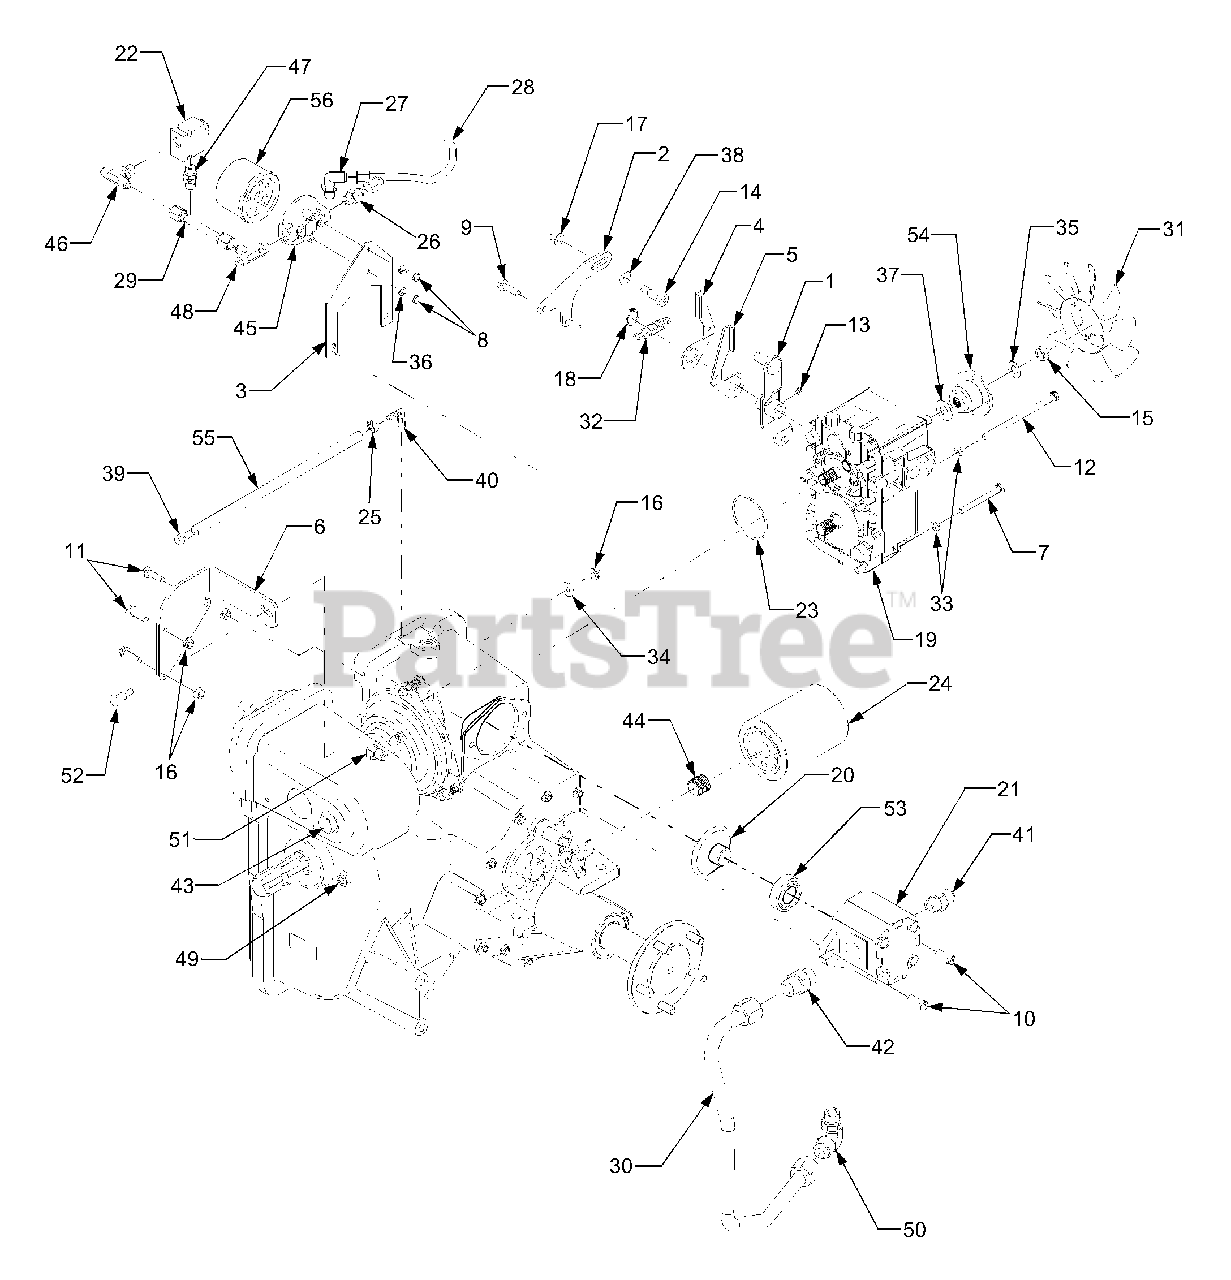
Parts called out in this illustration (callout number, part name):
1	Arm, Hydro
2	Bracket, Return
3	Bracket, Filter Mounting
4	Arm, Neutral - RH
5	Arm, Neutral - LH
6	Bracket, Clutch Torque
7	Screw, Hex Cap, 5/16-18 x 3.0 GR5
8	Screw, Hex Cap, 1/4-20 x .62 GR5
9	Screw, Hex Wash. Hd. Tapp, 5/16-18 x 1.25 GR5
10	Screw, Socket Hd. 3/8-16 x 1.0
11	Screw, Hex Flange, 5/16-18 x 1.5 GR5
12	Screw, Hex Cap Lock, 5/16-18 x 5.5 GR5
13	Screw, Set - Lock 5/16 x .5 GR5
14	Screw, Shoulder, .497 x .750: 3/8-16
15	Nut, Hex Patch Lock, 1/2-20
16	Nut, Hex Flange Lock, 5/16-18 GR5
17	Nut, Hex Flange Lock, 3/8-16
18	Ring, Retaining
19	Pump, Hydrostatic Transmission
20	Gear, Bevel, 35T
21	Pump, Auxiliary Hydraulic
22	Valve, Check
23	O-Ring, 2.425 ID x .103
24	Filter, Oil - Hydraulic System
25	Clamp, Hose
26	Fitting, Straight
27	Fitting, 90 Degree
28	Tube, Hydro Inlet
29	Tube, Filter Inlet
30	Tube, Aux. Pump Inlet
31	Fan, Transmission Cooling
32	Spring, Extension, .50 x 1.975 x.072
33	Washer, Lock, 5/16
34	Washer, Bell., .34 x .872 x .06
35	Washer, Belleville
36	Washer, Lock, 1/4
37	Washer, Flat, .56 x 1.0 x .04
38	Washer, Thrust, .375 x .812 x .06
39	Vent, 3/8 Dia
40	Fitting, Elbow
41	Fitting, Hyd. Adapter w/O-ring
42	Fitting, Hyd. Adapter w/O-ring
43	Fitting, Plug
44	Fitting, Filter Nipple
45	Adapter, Oil Filter
46	Fitting, Branch Tee
47	Fitting, Adapter
48	Fitting, Run Tee
49	Indicator, Oil Level Sight
50	Fitting, Elbow
51	Fitting, Elbow
52	Screw, Shoulder, .437 x .54
53	Bearing, Ball
54	Adapter, Hydro Pump
55	Hose, Vent
56	Filter, Hydro Pump
